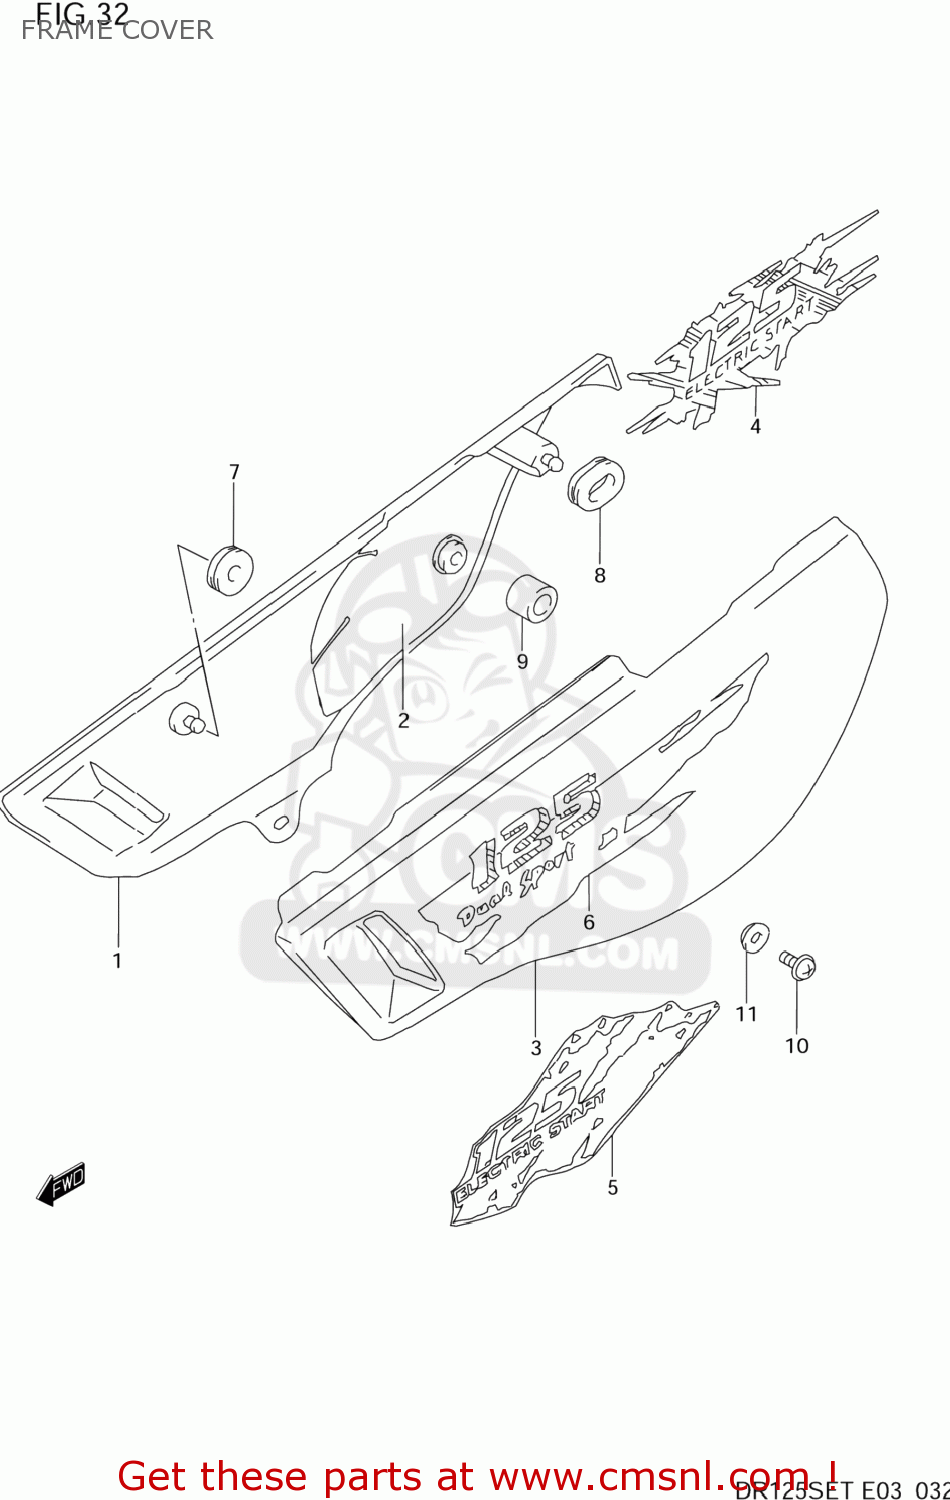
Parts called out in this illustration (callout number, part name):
1	COVER,FRAME,R(WHITE)
2	SHIELD,FRAME COVER,R
3	COVER,FRAME,L(WHITE)
4	EMBLEM, FRAME COVER
5	TAPE,FRAME COVER
6	TAPE,FRAME COVER,R
7	CUSHION
8	CUSHION
9	CUSHION
10	SCREW(6X16)
11	WASHER
